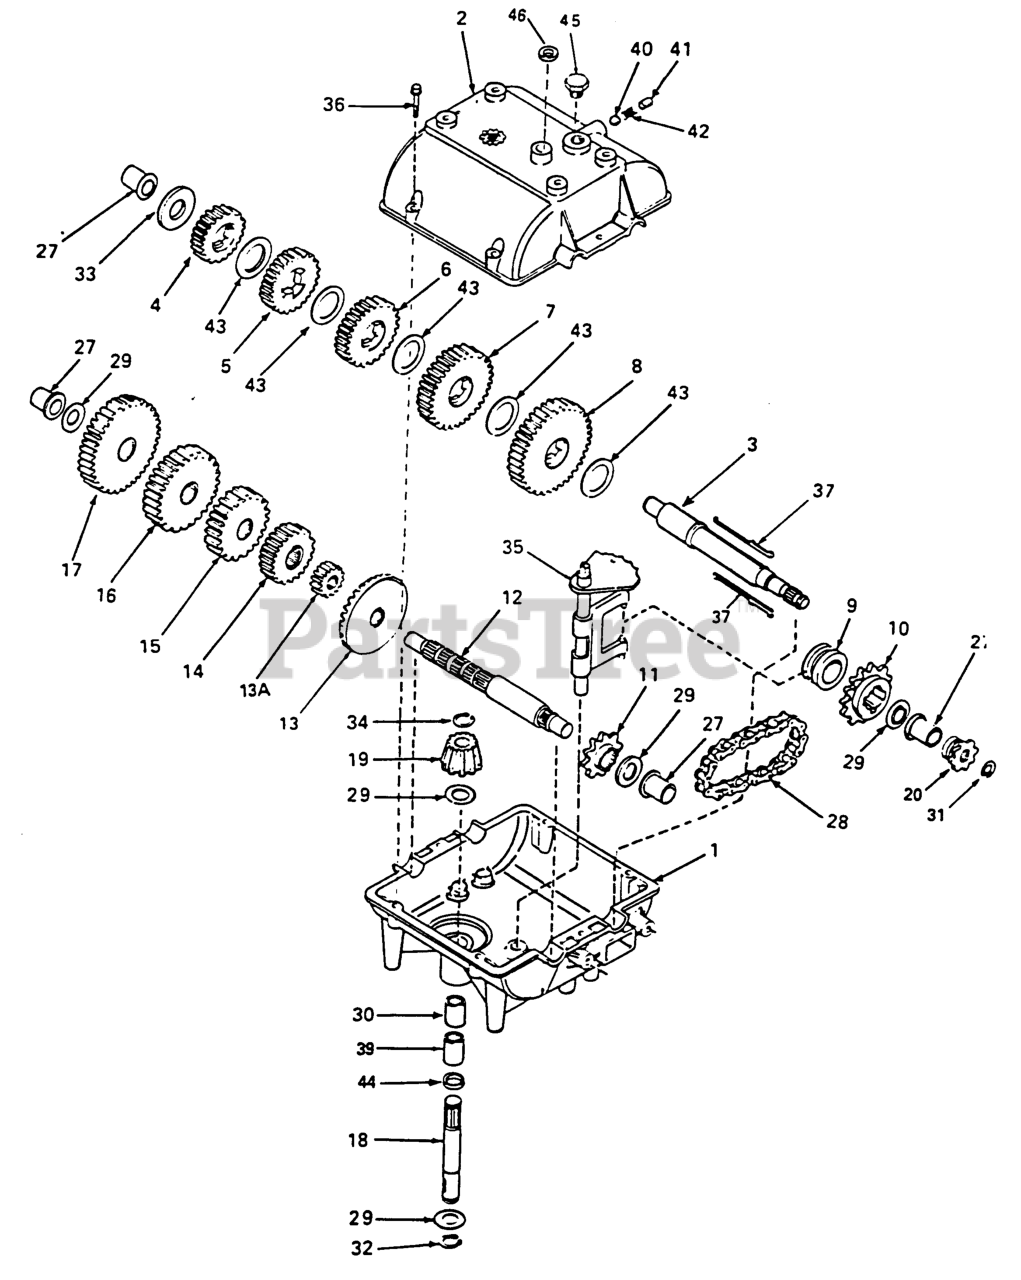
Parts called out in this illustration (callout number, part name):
1	Case, Transmission
3	Shaft, Output
6	Gear, Spur (25 Teeth)
7	Gear, Spur (30 Teeth)
8	Gear, Spur (35 Teeth)
9	Collar, Shift
10	Sprocket (18 Teeth)
11	Sprocket (9 Teeth Sprocket)
12	Shaft, Counter
13	Bevel Gear (42 Teeth)
13A	Gear, Spur (15 Teeth)
14	Gear, Spur (20 Teeth)
15	Gear, Spur (25 Teeth)
16	Spur (28 Teeth Gear)
18	Input Shaft (3-11/16" Long)
27	Bushing, Flanged
28	Chain, Roller (No. 41 Chain, 24 Links)
29	Washer, Thrust
30	Bearing, Needle
31	Ring, Retaining
32	Ring, Retaining
34	Ring, Retaining
35	Rod & Fork Assy., Shift
36	Screw, Flanged Hex Hd. Thr'd Forming 1/4-20 X 1-1/4
37	Shift Key
39	Bearing, Needle
40	Steel Ball, 5/16" Dia.
41	Set Screw, 3/8-16 X 3/8"
43	Washer, Thrust
44	"O" Ring
45	Plug, Threaded
46	Seal, Square Cut
